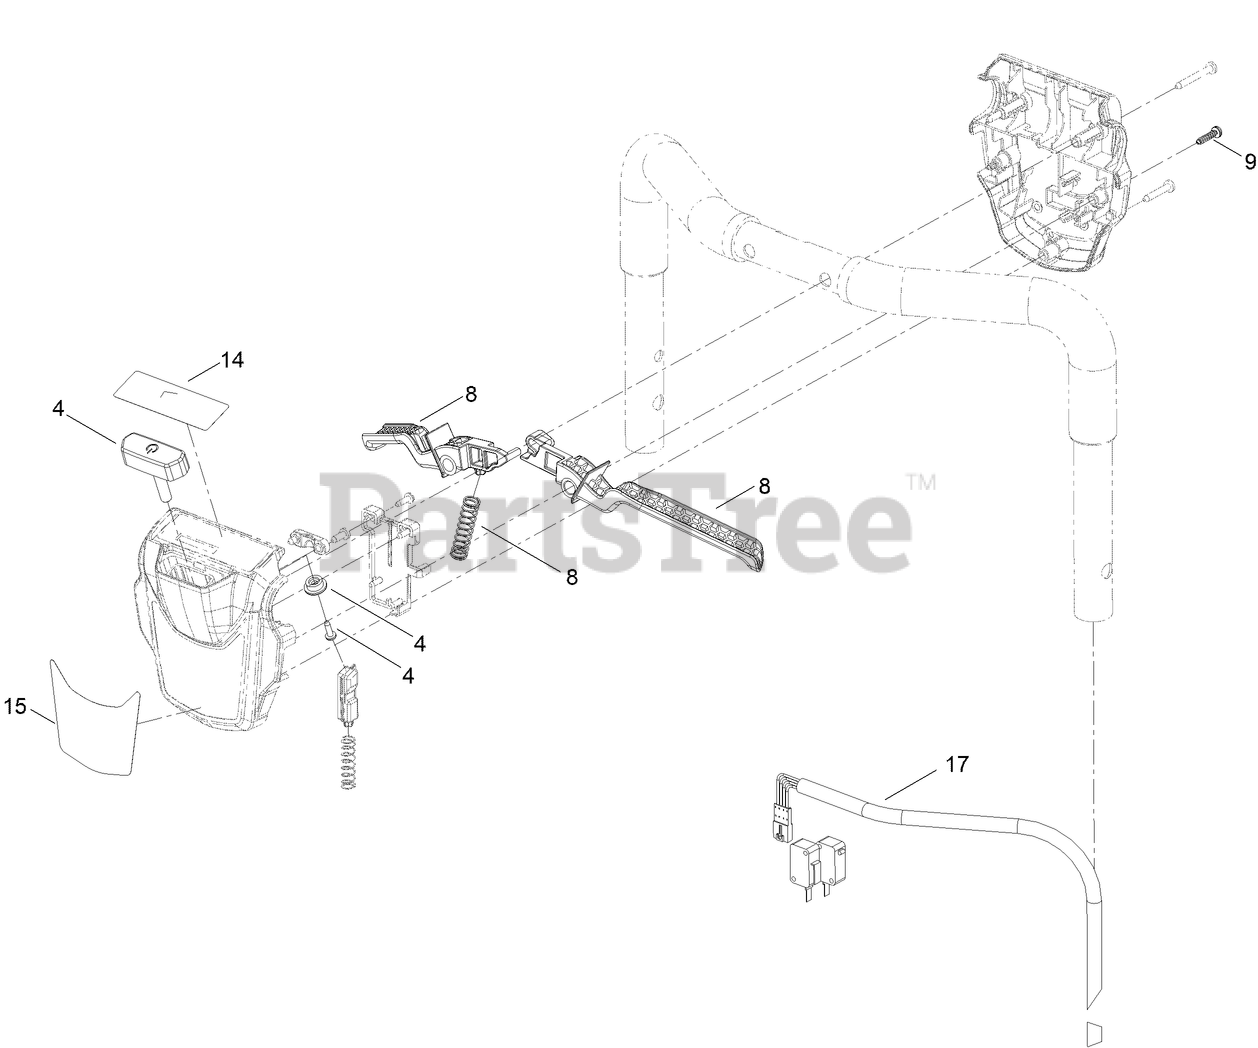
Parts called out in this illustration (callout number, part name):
4	TOP BUTTON KIT
8	UPPER LEVER KIT (36)
9	SCREW-T
14	DECAL - BOOST KEY MAT
15	DECAL - VOLTA HANDLE
17	WIRING LOOM, PUSH
